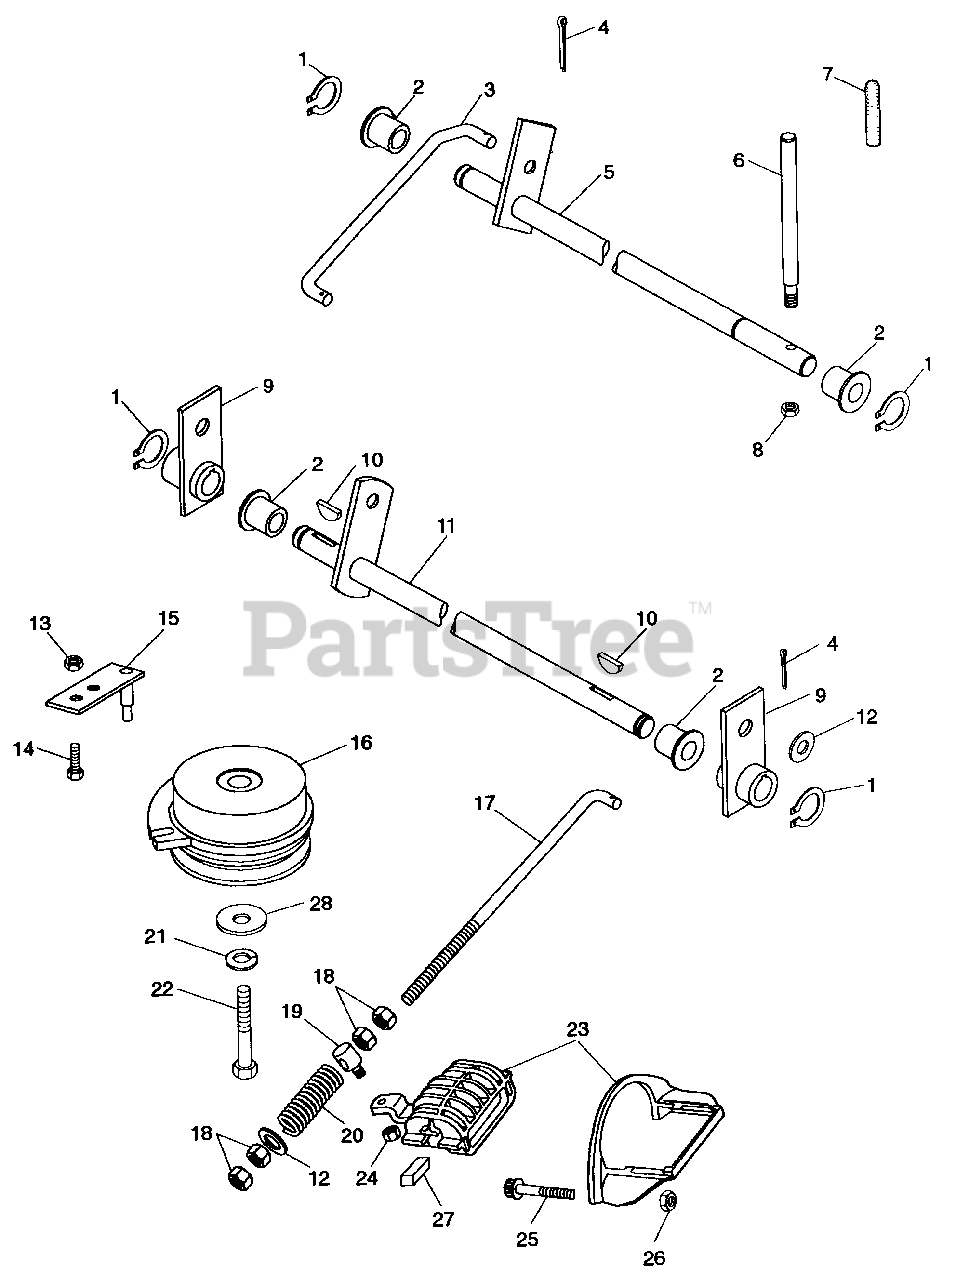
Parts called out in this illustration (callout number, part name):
1	RG, RTNG-EXT .625 X .050
2	BSHG-FLG .630 X 1.000 X .625 HY
3	ROD, BRAKE ACTUATING
4	PIN-COTR .09 X .75 PL
5	WLDMT, BRAKE ACTUATING SHAFT
6	LVR. PTO ACTUATING
7	GRIP, HAND CLUTCH LEVER
8	NUT-LK-NYL .312-18 PL
9	WLDM'T BRAKE ARM
10	KEY-WDRF .19 X .75 HRD #9
11	WLDM'T, BRAKE CROSS SHAFT
12	WSHR-FL-STL .406 X .812 X .065 PL
13	NUT-LK-NYL .375-16 W/INSR
14	BLT-HEX .38-16 X 1.125 GR 5
15	WLDM'T ELECT CLUTCH ANCHOR
16	ELECTRIC CLUTCH
17	ROD, BRAKE
18	NUT-HEX .375-16
19	PIVOT, BRAKE ROD
20	SG-COMP .142 X .710 X 2.00
21	WSHR-LOCK .44 REG
22	HHCS, 7/16-20 X 3.0, PL GR 5
23	BRK, DISC R.H.
23	BRK, DISC L.H.
24	NUT-LK .312-18 GR A PL
25	SCR, FLANGE .50-13 X 2.75
26	NUT-LK-NYL .50-13 PL
27	PAD SET, DISK BRAKE
28	WSHR-SPECIAL .469 X 2.00 X .250
